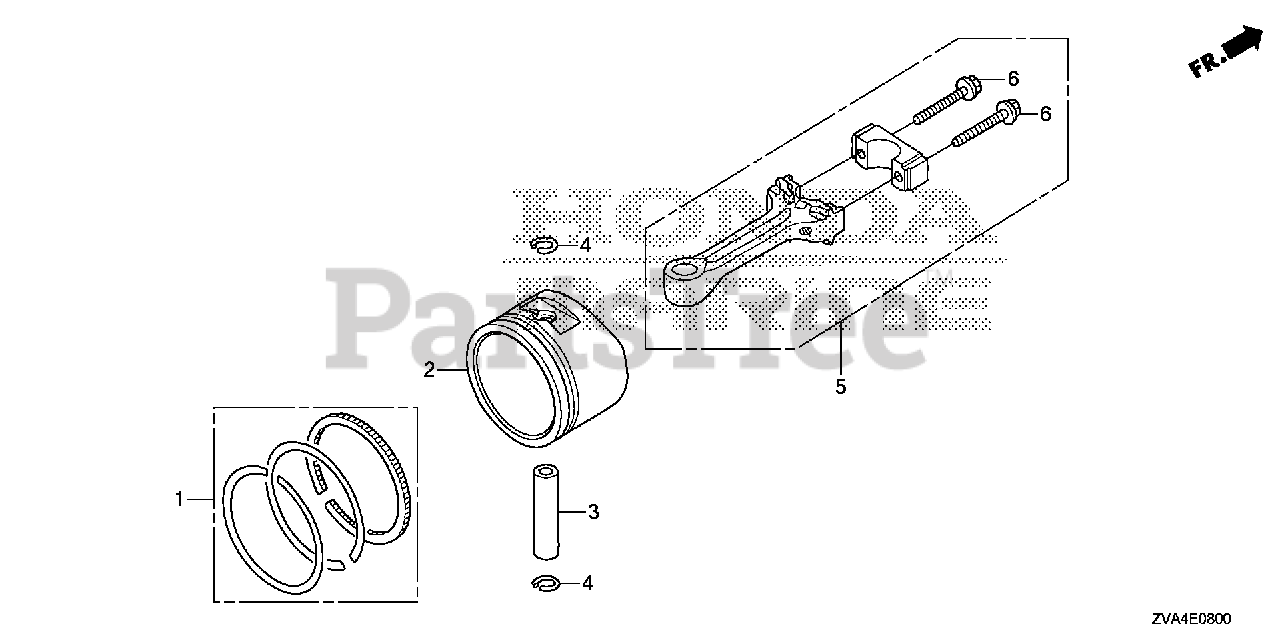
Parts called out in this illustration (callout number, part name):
1	RING SET, PISTON (STD)
2	PISTON (STD)
3	PIN, PISTON
4	CLIP, PISTON PIN (10MM)
5	ROD ASSY., CONNECTING
6	BOLT, CONNECTING ROD
